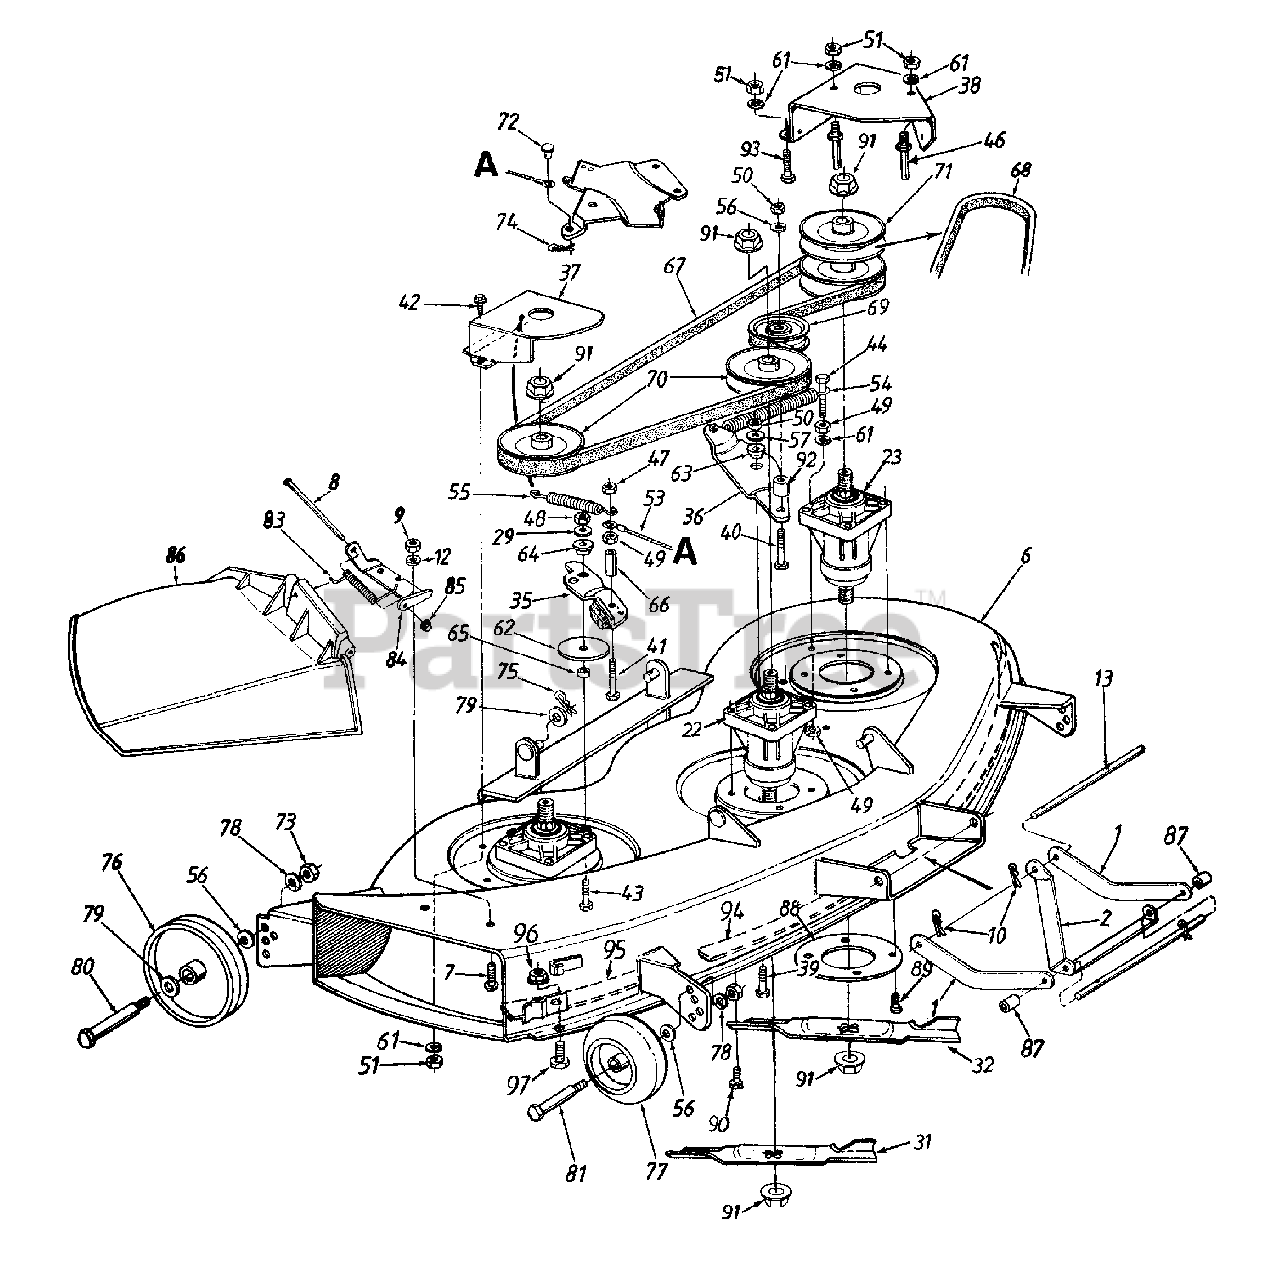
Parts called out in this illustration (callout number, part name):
8	Hinge Pin
9	Hex Nut 1/4-20 Thd. (Gr. 5)
10	Hairpin Clip
12	Bell-Wash. 1/4" I.D.
13	Deck Connecting Rod
22	Spindle Ass'y. (R.H. & Center)
23	Spindle Ass'y. (L.H.)
29	Lock Wash. 5/16" I.D.
31	Blade 14.88" Lg. (Middle)
32	Blade 16.28" Lg. (R.H. & L.H.)
35	Deck Brake Brkt. Ass'y.
36	Idler Bracket
39	Hex Bolt 3/8-24 x 1.0" Lg.
40	Hex Bolt 3/8-24 x 2" Lg.
41	Hex Bolt 1/4-28 x 1.75" Lg.
42	Hex Wash. Hd. Tap-Scr. 1/4-20 x .5"
43	Hex Bolt 5/16-24 x 1.5" Lg. (Grade 5)
44	Hex Bolt 1/4-28 x 1.5" Lg.
46	Belt Guard Pin 1/4" Dia.
47	Hex Cent. L-Nut 1/4-28 Thd.
48	Hex Nut 5/16-24 Thd.
49	Hex Nut 1/4-28 Thd.
50	Hex Nut 3/8-24 Thd.
51	Hex Nut 1/4-20 Thd. (Gr. 5)
53	Brake Cable Ass'y.
54	Extension Spring 6.17" Lg.
55	Extension Spring 3.97" Lg.
56	Bell-Wash. .38" I.D. x .88" O.D.
57	Bell-Wash. .39" I.D. x 1.13" O.D.
61	L-Wash. 1/4" I.D.
62	Fl-Wash. 5/16" I.D. x 3" O.D.
63	Shld. Spacer .625" I.D.
64	Shld. Spacer
65	Spacer .34" I.D.
66	Spacer .326" I.D.
67	V-Belt
68	V-Belt
69	Fl-Idler Pulley 3.5" O.D.
70	Pulley 5.0" Dia.
71	Double Pulley 5.0" Dia.
72	Clevis Pin 1/4" Dia. x .53" Lg.
73	Hex Nut 3/8-16 Thd.
74	Intern. Cotter Pin 5/16" Dia.
75	Intern. Cotter Pin 3/8 Dia.
76	Deck Wheel 5" Dia.
77	Deck Wheel w/Insert 5" Dia.
78	L-Wash. 3/8" I.D.
79	Fl-Wash. .531" I.D.
80	Shoulder Bolt .498" Dia. x 1.64" Lg.
81	Shoulder Bolt
83	Torsion Spring
84	Hinge Mtg. Brkt.
85	Push Nut
86	Chute Ass'y. Comp.
87	Spacer 5/8" I.D. x 7/8" O.D.
90	Hex Wash. Hd. Scr. 5/16-18 x .75" Lg.
91	Hex Flange Nut 5/8-18 Thd.
92	Spacer .38" I.D.
93	Hex Bolt 1/4-20 x .5" Lg.
96	Hex Sems Nut 1/4-20 Thd.
97	Carriage Bolt 1/4-20 x .5" Lg.
17258A-0648	Deck Belt Cover, 46" Black - TECH GRAY (0648)
17258A-0665	COVER:BELT:DECK 46 - YARDMAN GREEN (0665)
